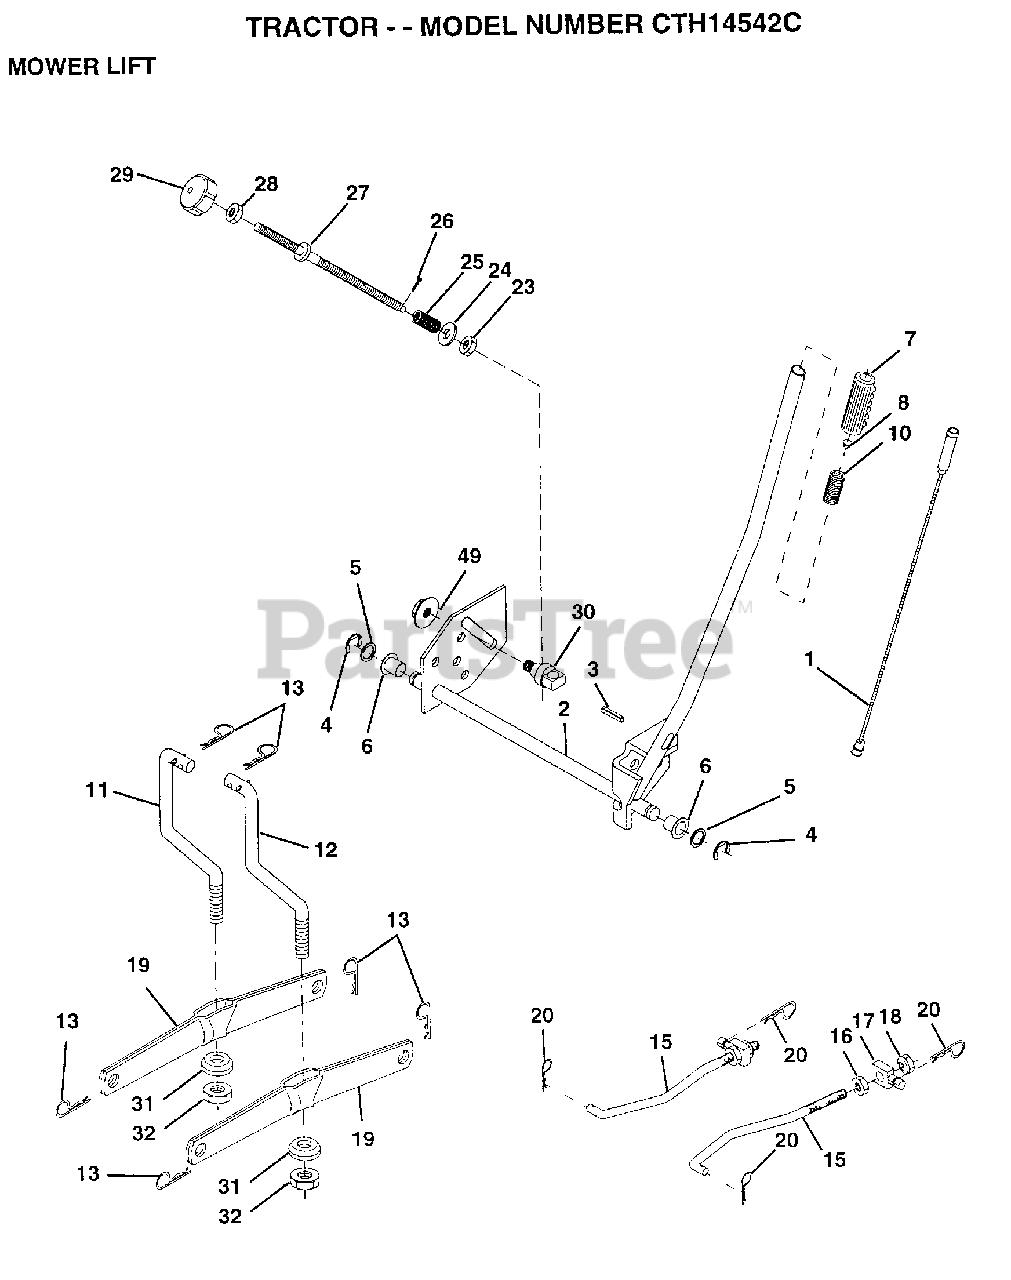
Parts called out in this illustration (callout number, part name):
1	WIRE.ASM.INNER
2	SHAFT.ASM.LIFT.RH
3	PIN GROOVE
5	WASHER
6	NYLON BEARING
7	GRIP
15	LINK.FRONT
16	NUT
17	TRUNION
18	NUT.LK.W/WSH.1/2.
19	ARM SUSP REAR
20	RETAINER.SPRING
23	NUT T
24	WASHER
25	SPRING.COMP.INF.H
27	ROD.ADJ.LIFT
28	NUT
29	KNOB INF 3/8-16
30	TRUNNION
31	BEARING PVT LH
32	NUT.CROWNLOCK.3/8
49	NUT.HXFLG.LOCK.
